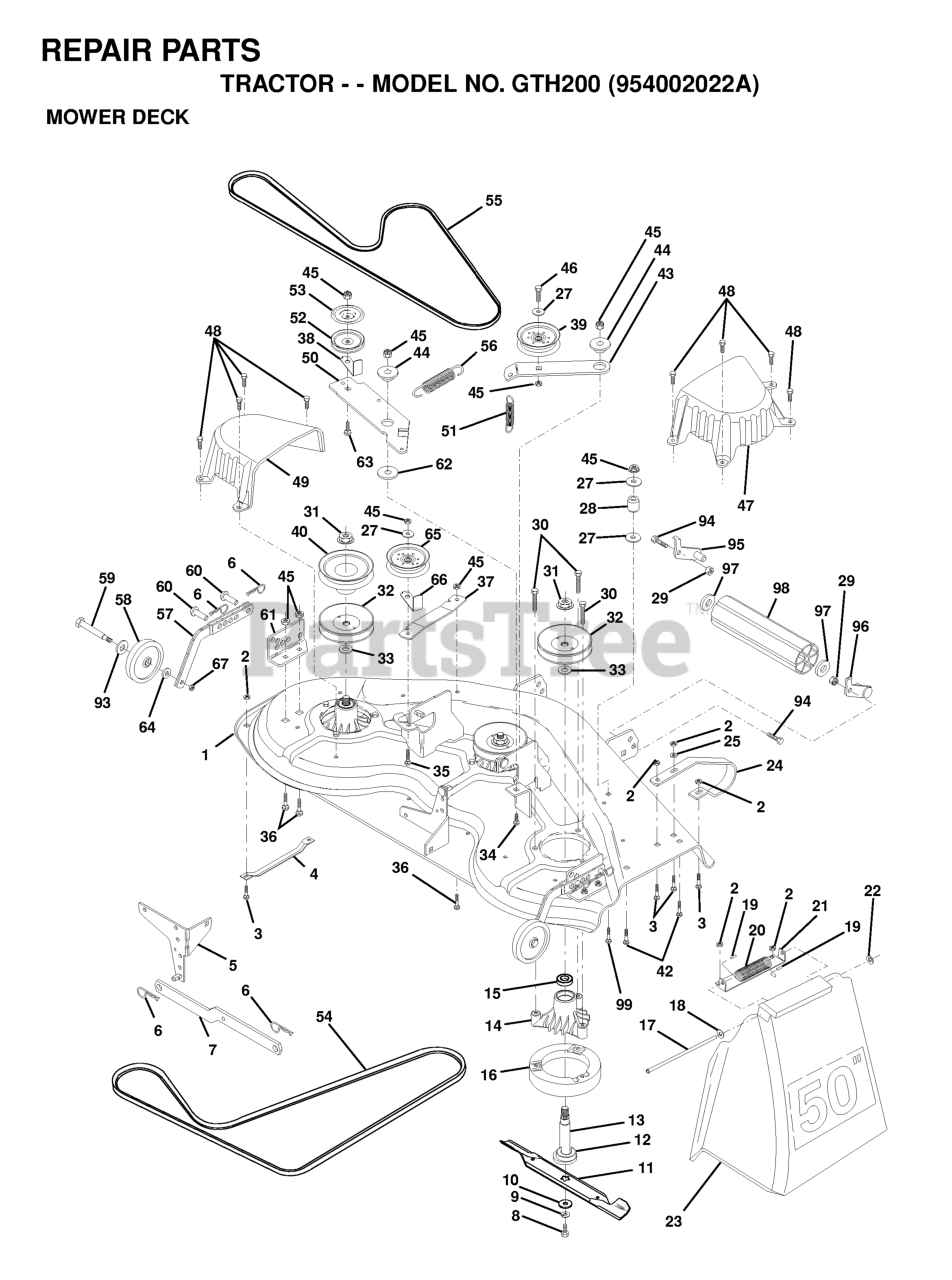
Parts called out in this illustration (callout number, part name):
1	DECK ASM MWR 50VT
2	LOCKNUT
3	BOLT.CARR.SQNK.5/16-18UNC.X3/4
4	RUNNER-LH M
5	BRACKET SWAY BAR
6	RETAINER-SPRNG RB
7	REAR SUSP ARM
8	BLADE BOLT
9	LOCKWASHER
10	WASHER.BLADE
11	BLADE.50".HI-LIFT
12	BEARING.BALL.#6204.(MANDREL)
13	SHAFT.ASM.W/BEARING
14	HOUSING.MANDREL.44/46" VENT
16	STRIPPER
17	ROD-HINGE T
18	Washer 11/32 x 5/8 x 16 Ga SD
19	CAP-SLEEVE LT
20	SPRING TORSION
21	BRACKET, DEFLECTOR
22	NUT PUSH M
23	SHIELD.DEFLECTOR.MOWER.50"BLK.
25	WASHER M
27	WASHER
28	IDLER SPRING SPACER
29	NUT
30	SCREW
31	NUT
32	MANDREL PULLEY
33	WASHER
34	BOLT.3/8-14X1.25
36	BOLT D
37	STIFFENER ARM
38	KEEPER
39	FLAT IDLER PULLEY
40	PULLEY.DRIVEN.44"
42	RP BOLT 5/16-18 X3/4 ZN/YEL GR
43	ARM.IDLER.SEC.44"
44	SPACER RETAINER
46	BOLT
47	COVER MANDRELL
48	SCREW.1/4-20X5/8
49	COVER.MANDREL.LH.44"
50	ARM.IDLER.PRIMARY
51	SPRING.SEC.44"VEN
52	PULLEY IDLER
53	SHIELD IDLER
54	V-BELT.PRMRY 46/50 VENT.BLK BK
55	BELT V SECONDARY
57	BAR.ASM.GUAGE.WHEEL
58	WHEEL.GAUGE.BLK.4.93
59	BOLT M
60	PIN.CLEVIS
61	BRACKET.GUAGE.WHEEL
62	HARDENED WASHER
63	BOLT.3/8-16X1.50
64	WASHER.5/16.FLAT.STE.STD.
65	IDLER-FLAT T
66	KEEPER
67	LOCKNUT
93	Washer 17/32 x 15/16 x 12 Gauge
94	BOLT
95	BRACKET LH (A)
96	BRACKET RH (B)
97	Washer 1 17/32 X 7/8 X 16 Ga
98	NOSE ROLLER
